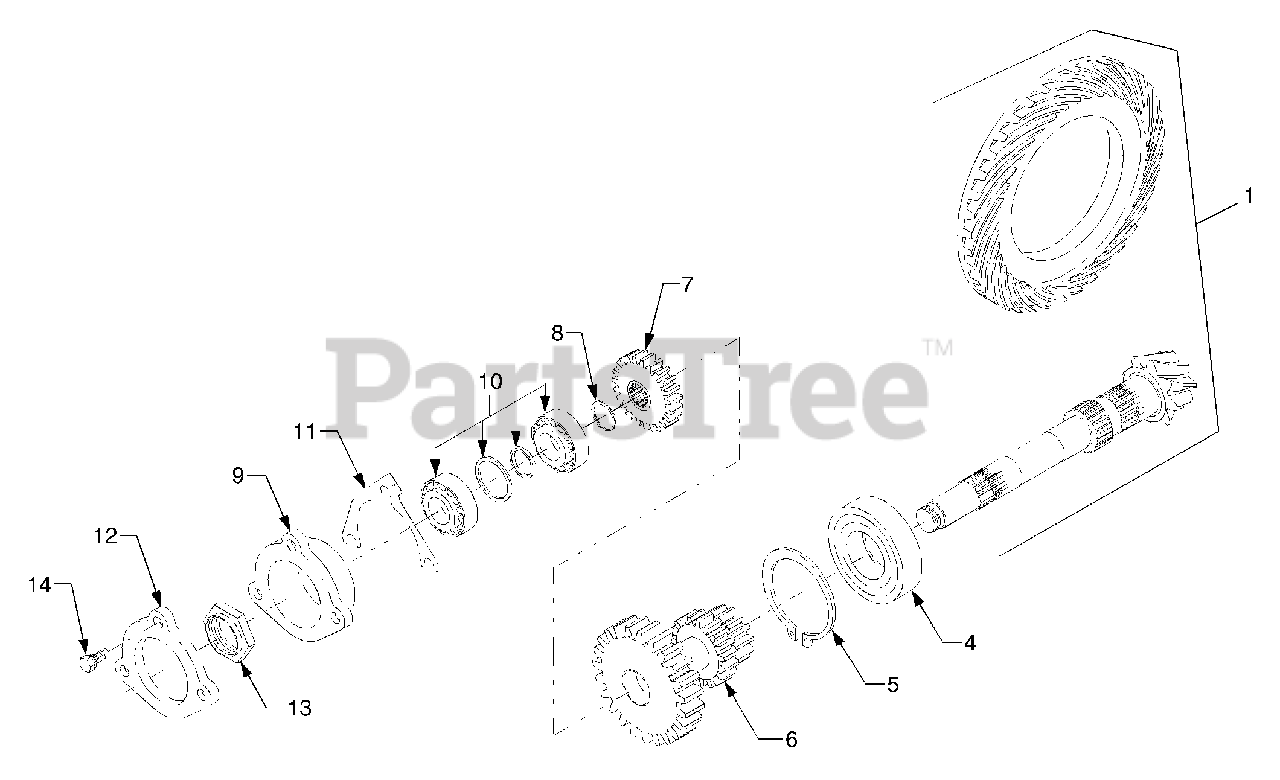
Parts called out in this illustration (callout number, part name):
1	Spiral Bevel Gear Ass'y
2	Gear, Spiral Bevel
3	Pinion, Spiral Bevel
4	Bearing, Roller
7	Gear, 25 Spur
9	Case, Bearing
10	Bearing, Taper Roller
12	Cover, Bearing
